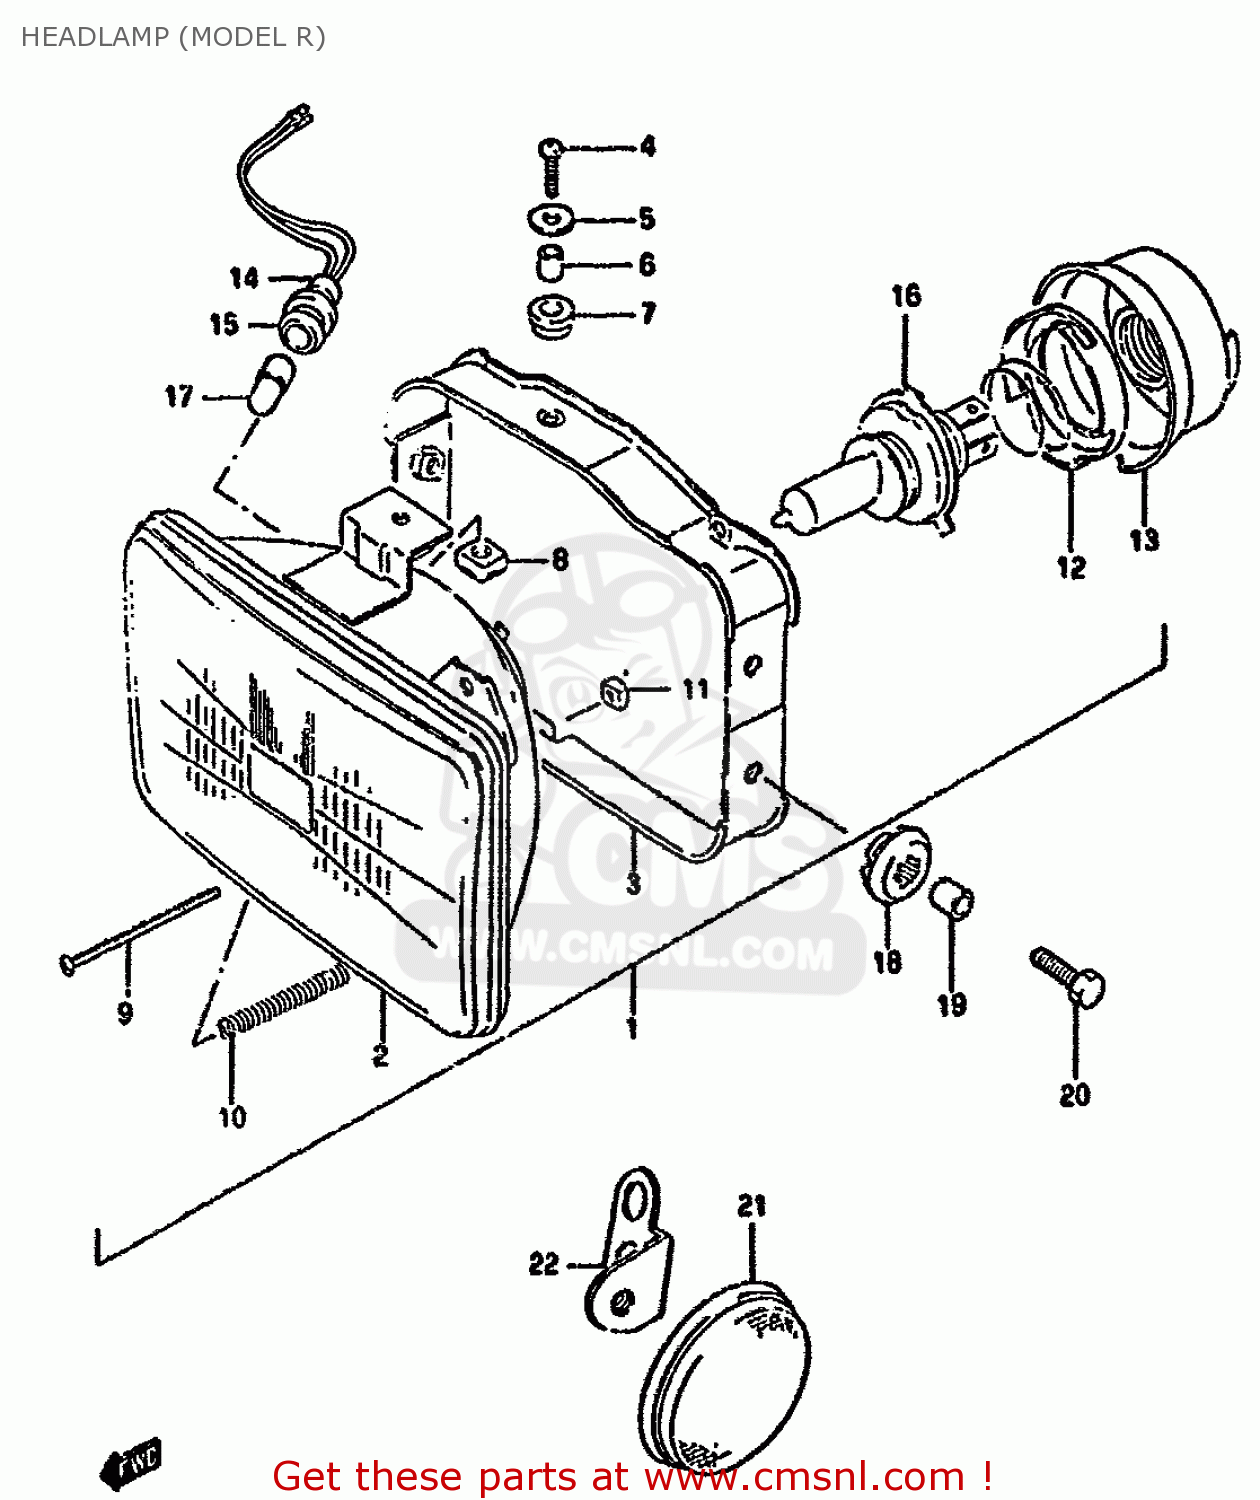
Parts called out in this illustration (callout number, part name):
1	HEADLAMP ASSY
2	LAMP UNIT
3	HOUSING
4	SCREW
5	WASHER
6	SPACER
7	CUSHION
8	NUT
9	SCREW
10	SPRING
11	NUT
12	HOLDER,BULB
13	COVER,SOCKET
14	SOCKET
15	JOINT,RUBBER
16	BULB(12V60/55W,H4)
17	BULB(12V4W)
18	CUSHION
19	SPACER(6.3X9.1X11.5)
20	BOLT(6X20)
21	REFLECTOR,REFLEX FR
22	BRACKET
